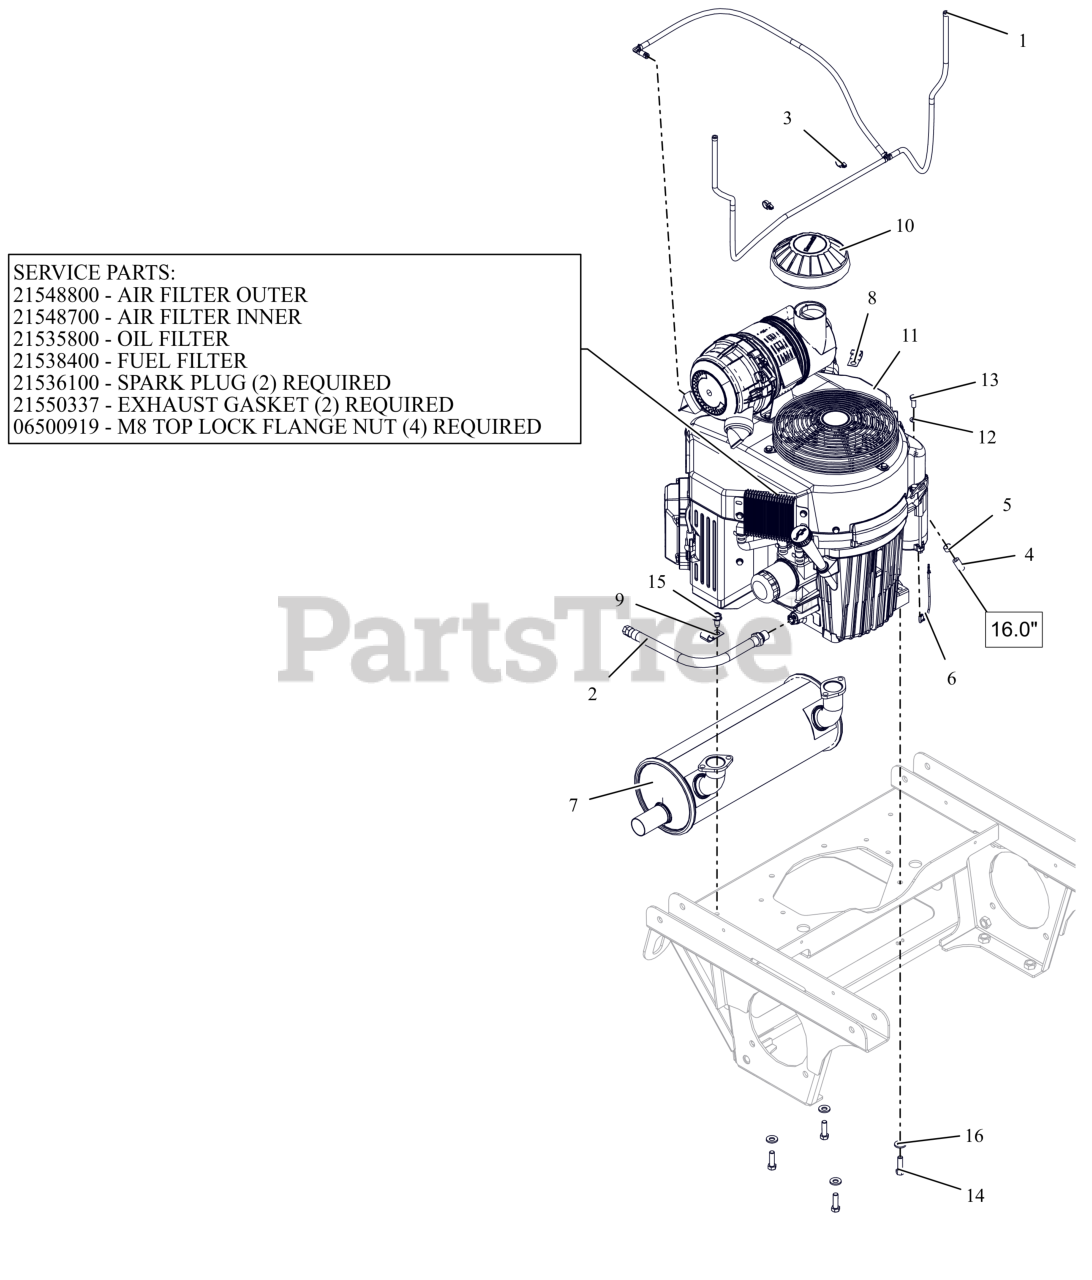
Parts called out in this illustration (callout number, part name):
1	ASM, VAPOR LINE
2	HOSE, OIL DRAIN
3	ROUTING CLIP (1/2" ID)
4	HOSE, .25 LOW-PERM BULK GAS
5	CLAMP, FUEL LINE
6	LEAD - STARTER SOLENOID
7	MUFFLER - 34HP KAWASAKI VERT.
10	CAP, AIR CLEANER INTAKE (2")
11	ENGINE-KAWASAKI FX921
11	FILTER, OUTER
11	FILTER, INNER - KAW
11	FUEL FILTER - KAWASAKI
11	PLUG, SPARK
11	GASKET, EXHAUST (11061-7061)
11	NUT-LK-TOP-FLG M8 ZCC
12	WSHR,LK-REG .312X.078 ZCC
13	BLT, HEX M8-1.25X20 G8.8 ZCC
14	BLT, HEX .38-16X1.25 G5 ZCC NT
15	SCR,TAP .375-16X.75 HWH TR ZCC
16	WASHER, 3/8" SPRING DISC
